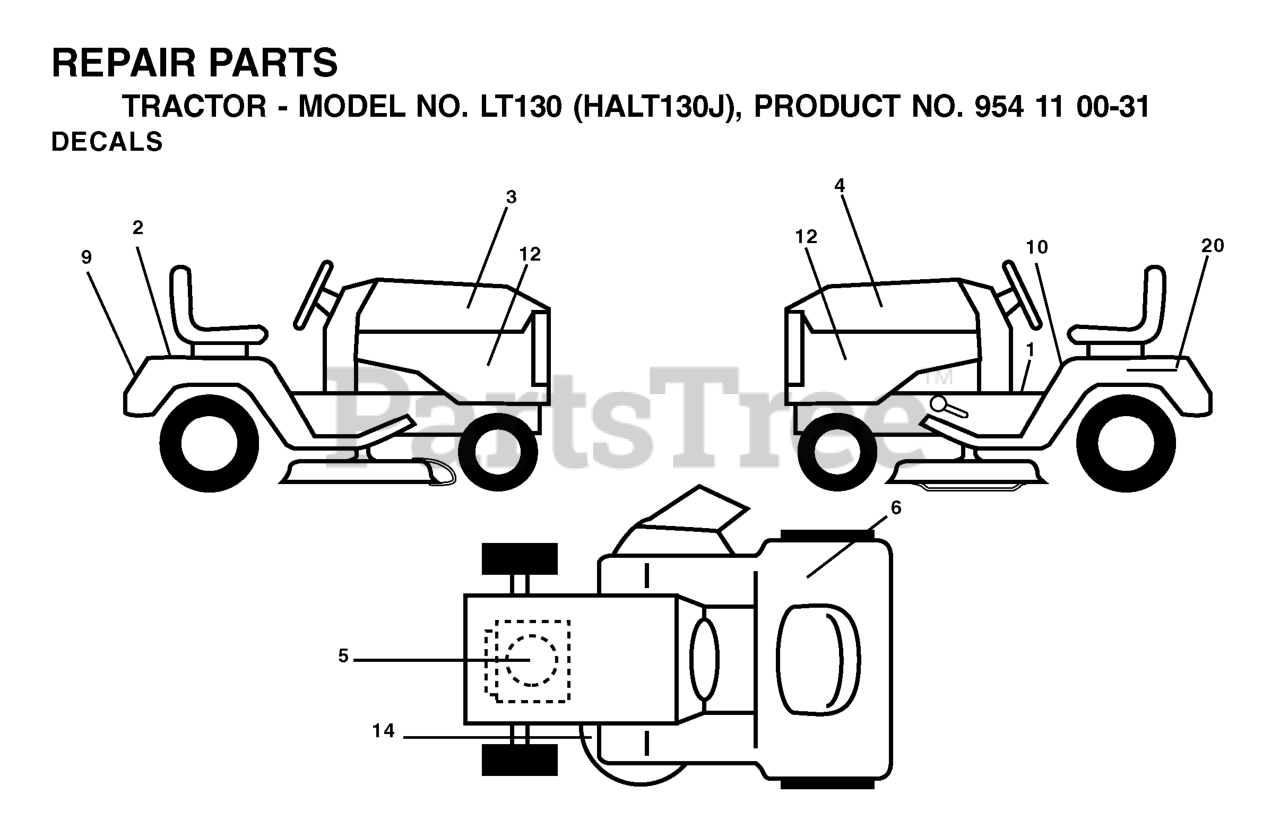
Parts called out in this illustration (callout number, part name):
1	WHEEL.STEER.HUSQ.SR.498.OVMLD
2	RP SUBASM.AXLE.CAST.NZTR.
4	SPINDLE WELDMENT.SPINDLE.LH.15
5	SPINDLE WELDMENT.SPINDLE.RH.15
6	THRUST WASHER
9	CAP.SPINDLE.BLACK
14	WASHER, LOCK 3/8
15	NUT CROWNLOCK 3/8-24
16	SHAFT.STEER.2HIGH.SPLND.PLATED
19	PLATE.STEER.DDL.NLT/NG
21	ADAPTER.WHEEL.STEER.SPLND.ALUM
22	BEARING.SUBASM.SHAFT.STEER.LOW
26	INSERT.CAP.WHL.STRG.HUSQ.PREM
28	SCREW, 3/8-16X3/4
35	GEAR GEAR.SECTOR.TEX.NZTR
45	WASHER 9/16"ID, 2 3/8"OD
50	NUT LOCK FLG 3/8-16 UNC
53	WASHER.HARDENED
58	BOLT.SHOULDER.SECTOR.P
59	WASHER.THURST.SECTOR.S
60	NUT FLANGE LOCK 5/8-11
61	LINK SUBASM.LINK.DRAG.LH.NZTR
62	TUBE TUBE
63	SCREW
64	RETAINER.CLIP.SPRING.S
66	BOLT HEX FGHD 7/16-14 X 3 SERR
67	BUSHING.PM.FRONT AXLE
68	NUT.LOCK.FLANGE.7/16
69	WASHER.1.5X.505X.118
70	BRACKET.FRT.DECK.SUSP.RR.MT431
75	PINION.ZINC PLATED
76	SCREW HEAD SOCKET LRVB
80	THRUST WASHER
81	LINK SUBASM.LINK.CROSS.NZTR
82	SUBASM;PIVOT;BOLT;NZTR
85	PIVOT SUBASM.PIVOT.RH.NZTR
86	PIVOT SUBASM.PIVOT.LH.NZTR
122	CAP.GEAR.SECTOR.TEX
